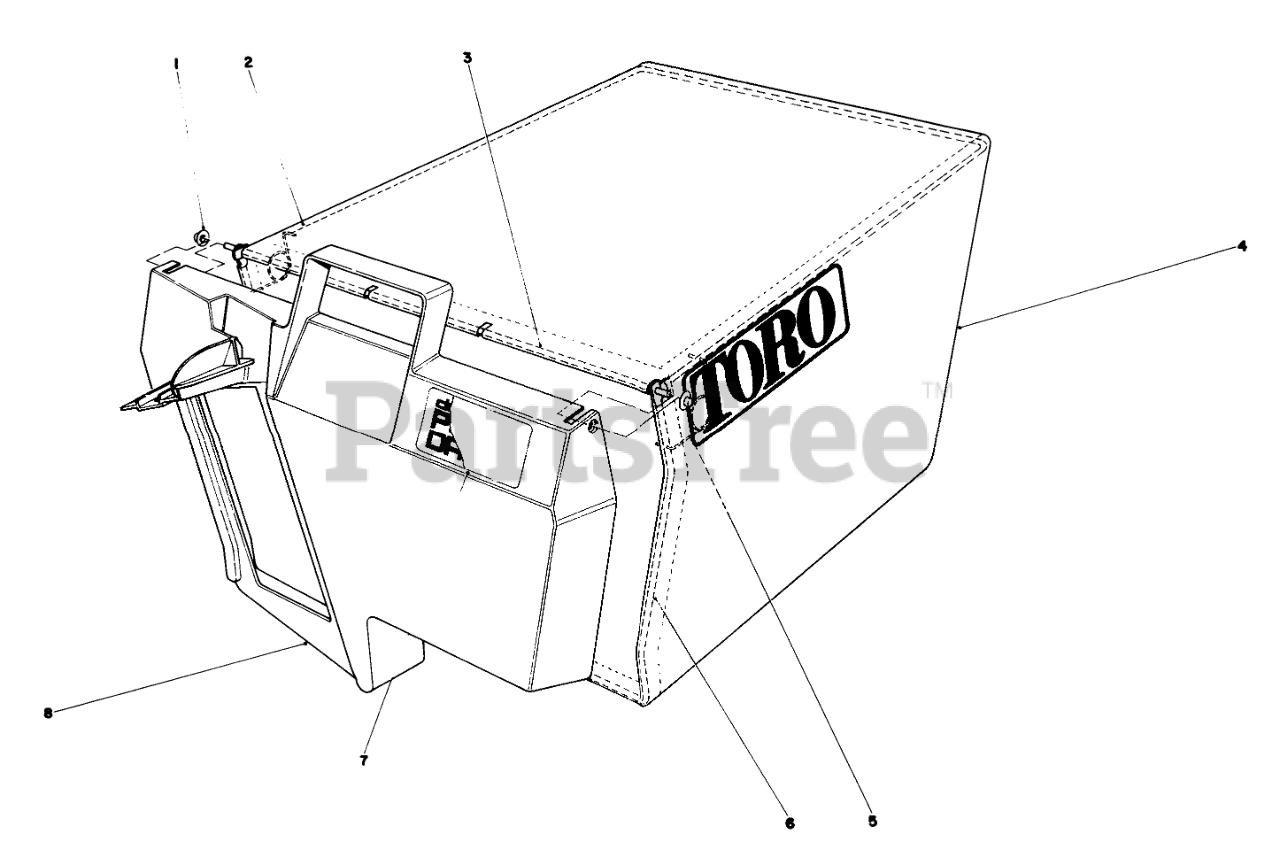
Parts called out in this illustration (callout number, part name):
1	NUT-PUSH
2	FRAME-BAG, UPPER
3	HingeBag Door
4	Bag
5	SPRING
6	FRAME-BAG
7	BAG DOOR DECAL
8	Door Grass Bag
